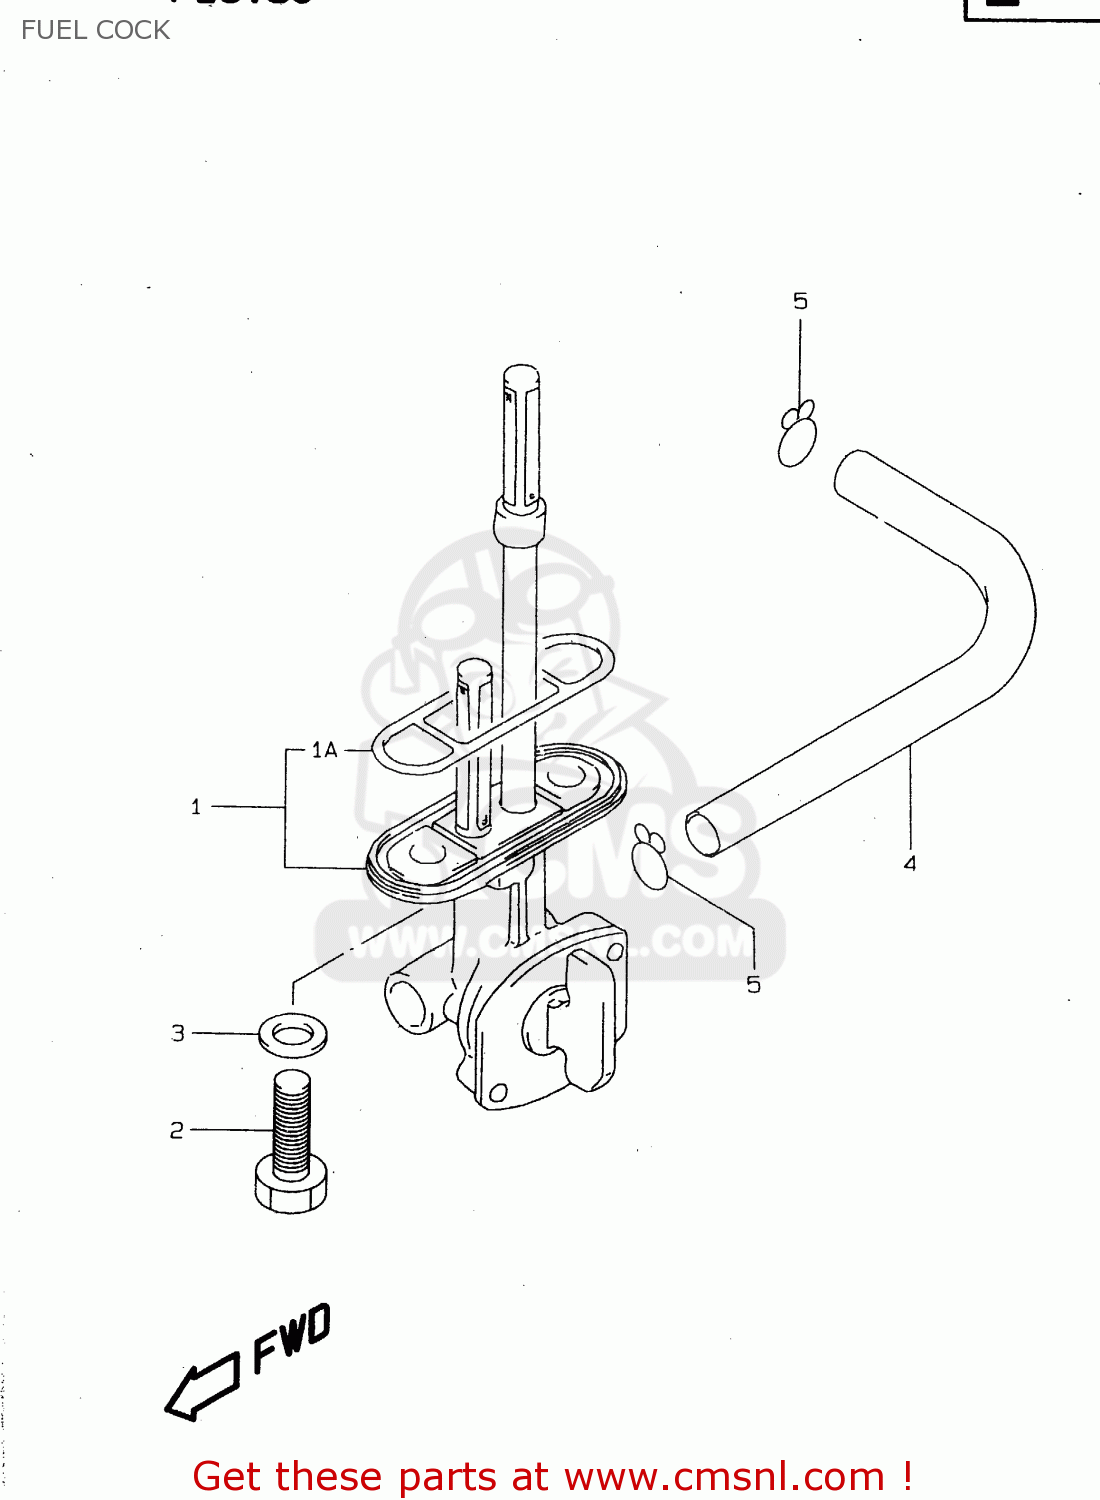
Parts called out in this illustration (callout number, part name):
1	COCK ASSY, FUEL
1A	GASKET,JOINT (NAS)
2	BOLT(6X20)
3	GASKET(6.4X11.5X0.8) (NAS)
4	HOSE(5X8.2X600)
5	CLIP
